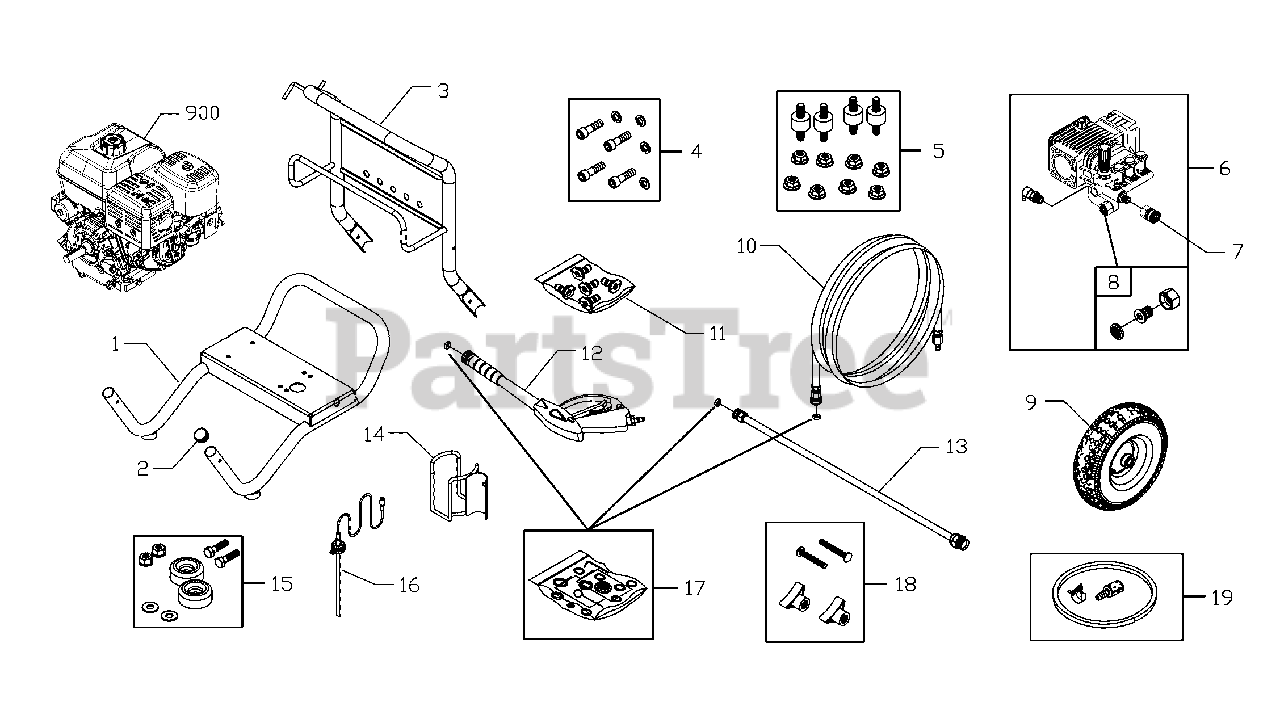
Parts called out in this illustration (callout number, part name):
4	KIT-PUMP MOUNTING HARDWARE
5	KIT-HRDWR ENGINE MOUNTING
7	FITTING
8	ADAPTER-GARDEN HOSE
11	KIT-QC NOZZLES
12	GUN
13	EXTENSION-QC
15	MOUNT-VIBRATION
17	KIT-O RING
18	KIT-HARDWARE HANDLE
